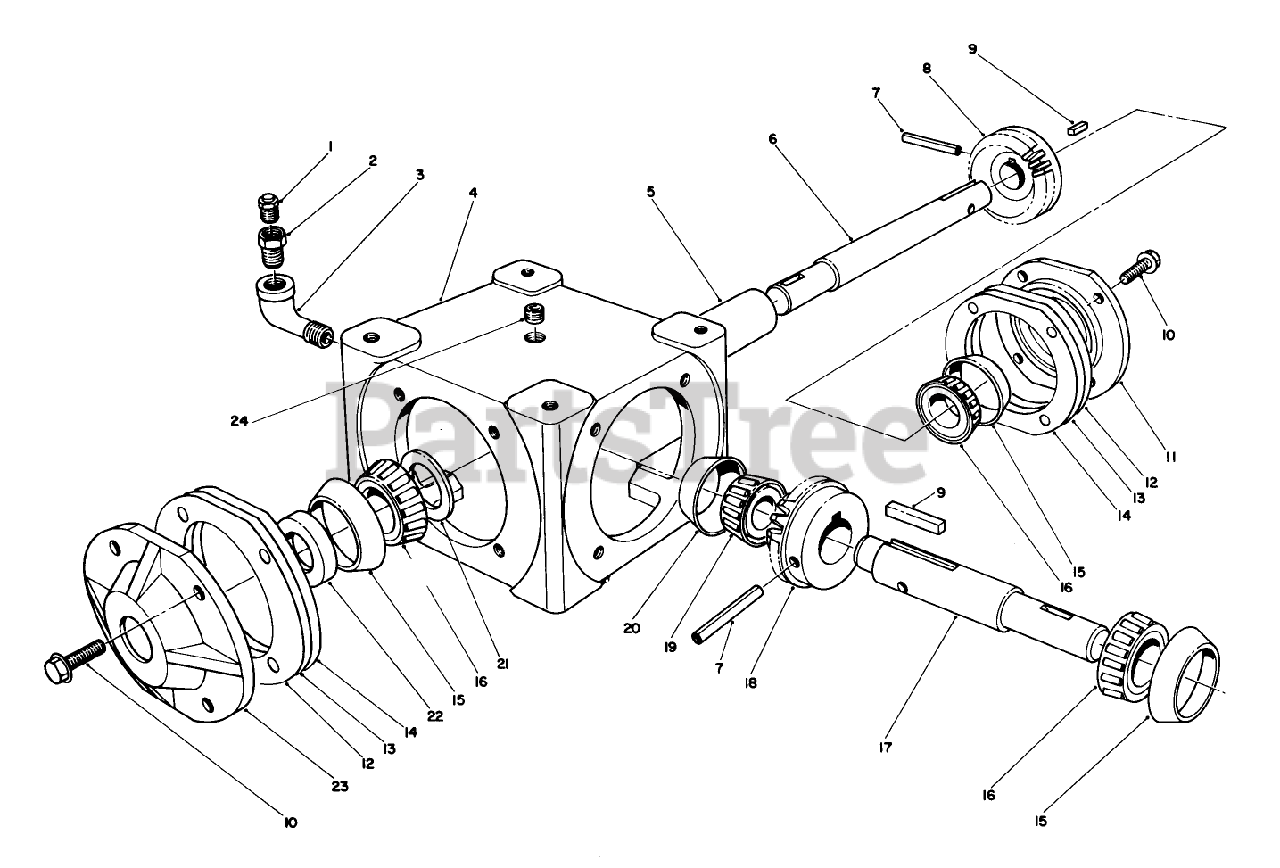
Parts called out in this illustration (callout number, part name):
2	BUSHING
5	SPACER
6	SHAFT
12	GASKET
13	GASKET
17	SHAFT
21	WASHER
